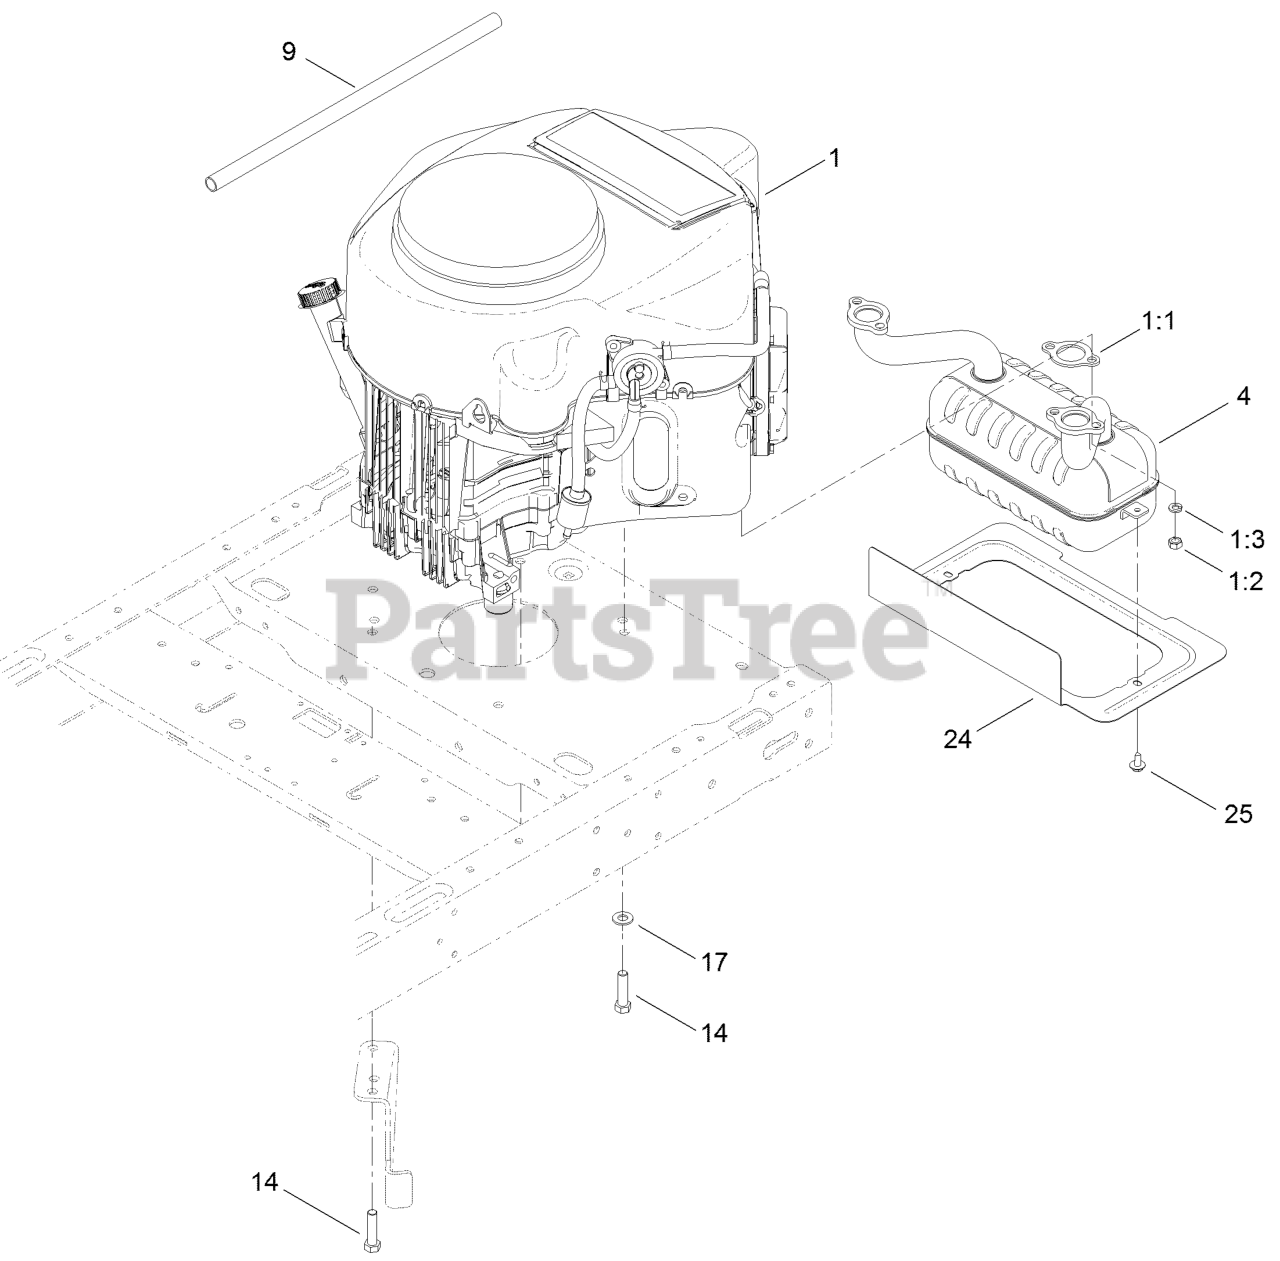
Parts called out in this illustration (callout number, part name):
1:1	GASKET-EXHAUST
1:3	WASHER-LOCK
4	MUFFLER-KAWASAKI
9	TUBE-DRAIN, OIL
14	BOLT-HH
17	WASHER-FLAT
24	SHIELD-HEAT
25	SCREW-HHFTF
